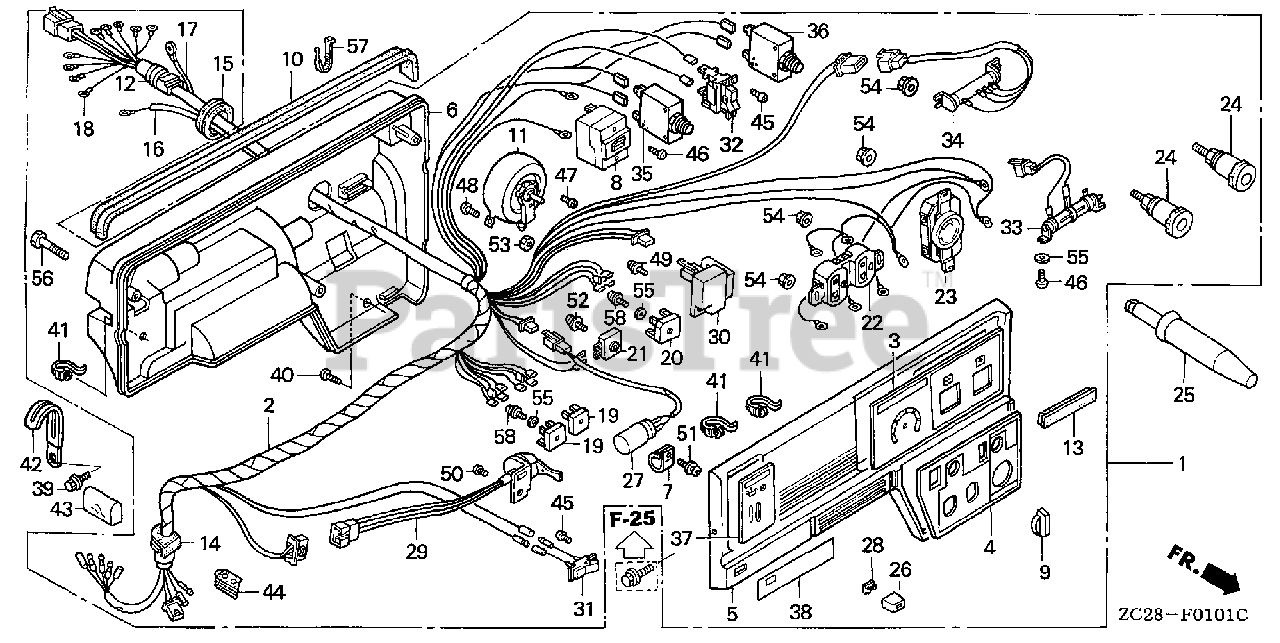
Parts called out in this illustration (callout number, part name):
1	BOX ASSY., CONTROL *R8* (BRIGHT RED)
2	WIRE HARNESS ASSY. (EW-A)
3	MARK, CURRENT CONTROL
4	MARK, A.C. OUT (EW-A)
5	PANEL, CONTROL *R8* (EW-A) (BRIGHT RED)
5	PANEL, CONTROL *R280* (EW-A) (POWER RED)
6	CASE, CONTROL *R8* (BRIGHT RED)
6	CASE, CONTROL *R280* (POWER RED)
7	HOLDER, CONDENSER
8	BREAKER, CIRCUIT (33.5A)
9	KNOB, ADJUSTING
10	RUBBER, CONTROL
11	RESISTOR, VARIABLE
12	GROMMET, A.C. WIRE
13	GROMMET, COVER
14	GROMMET, SWITCH WIRE
15	GROMMET, MAIN WIRE
16	WIRE A, WELDER TERMINAL (L=930MM 8X6) (+)
17	WIRE B, WELDER TERMINAL (L=700MM 6X6) (+)
18	WIRE C, WELDER TERMINAL (L=520MM 8X6) (-)
19	STACK, DIODE
20	DIODE
21	STACK, DIODE
22	RECEPTACLE (20A/125V)
23	RECEPTACLE (30A/125V)
24	RECEPTACLE, PANEL
25	CONNECTOR, MALE
26	KNOB, VALVE LEVER
27	CAPACITOR ASSY.
28	BUSH, CONTROL KNOB
29	SWITCH ASSY., ENGINE STOP
30	THROTTLE UNIT ASSY., AUTO
31	SWITCH ASSY., AUTO THROTTLE
32	SWITCH ASSY.
33	RESISTOR, ADJUSTABLE
34	RESISTOR
35	PROTECTOR, CIRCUIT (20A)
36	PROTECTOR, CIRCUIT (30A)
37	MARK, ENGINE SWITCH
38	MARK, AUTO-THROTTLE
39	BOLT, FLANGE (6X12) (CT200)
40	SCREW, GLOVE BOX
41	TIE, CABLE
42	CLIP, WIRE HARNESS
43	TUBE, WIRE
44	GROMMET, TUBE
45	SCREW, PAN (3X6)
46	SCREW, PAN (4X6)
47	SCREW, PAN (4X8)
48	SCREW, PAN (4X10)
49	SCREW-WASHER (5X12)
50	SCREW-WASHER (4X10)
51	SCREW-WASHER (5X14)
52	SCREW-WASHER (5X20)
53	NUT, HEX. (4MM)
54	NUT, FLANGE (4MM)
55	WASHER, PLAIN (4MM)
56	BOLT, FLANGE (6X40)
57	TIE, CABLE
58	SCREW-WASHER (4X20)
